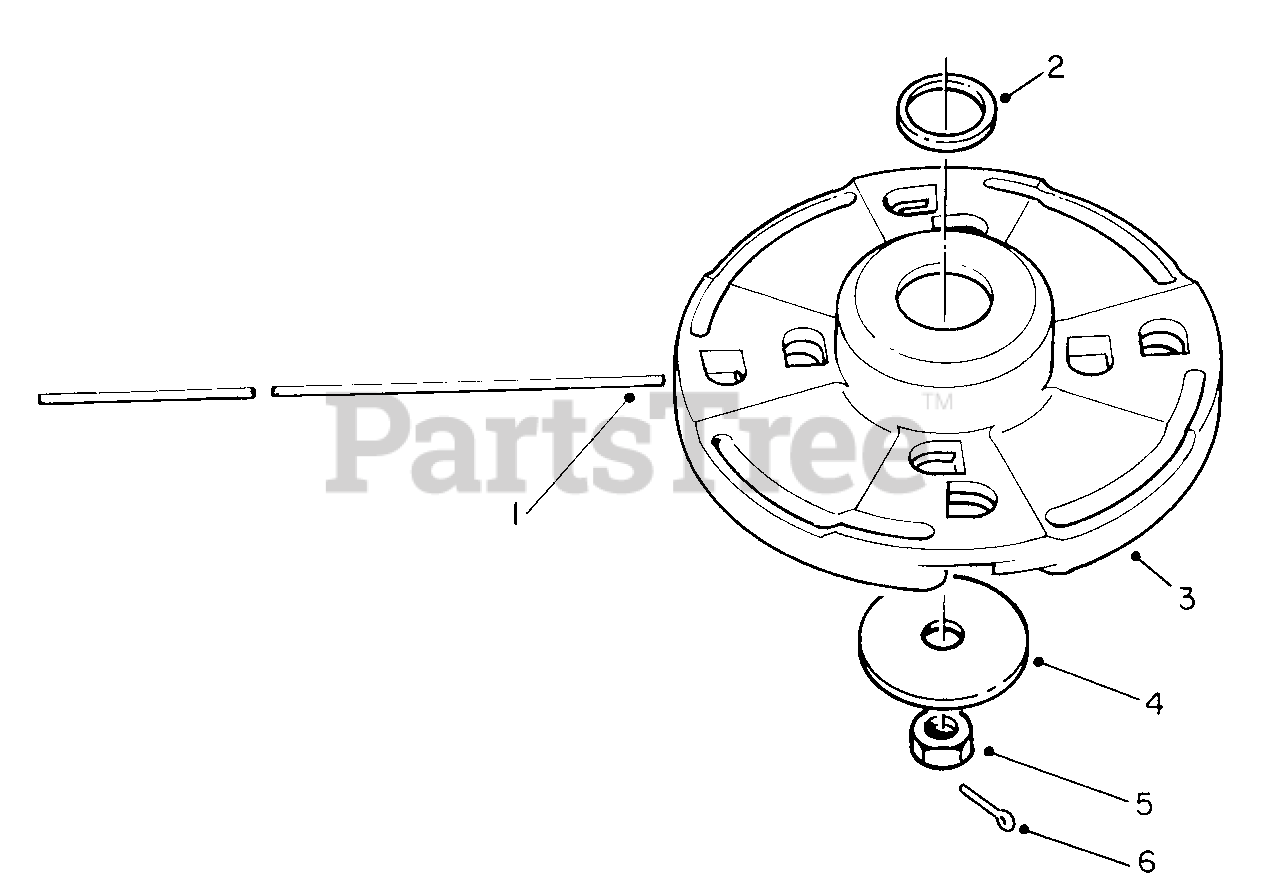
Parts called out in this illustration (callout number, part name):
1	.105 (100 Pcs.)(Optional)
2	Spacer
3	Head Assembly (Incl. Ref. #2)
4	Washer-Plate
6	Cotter Pin
